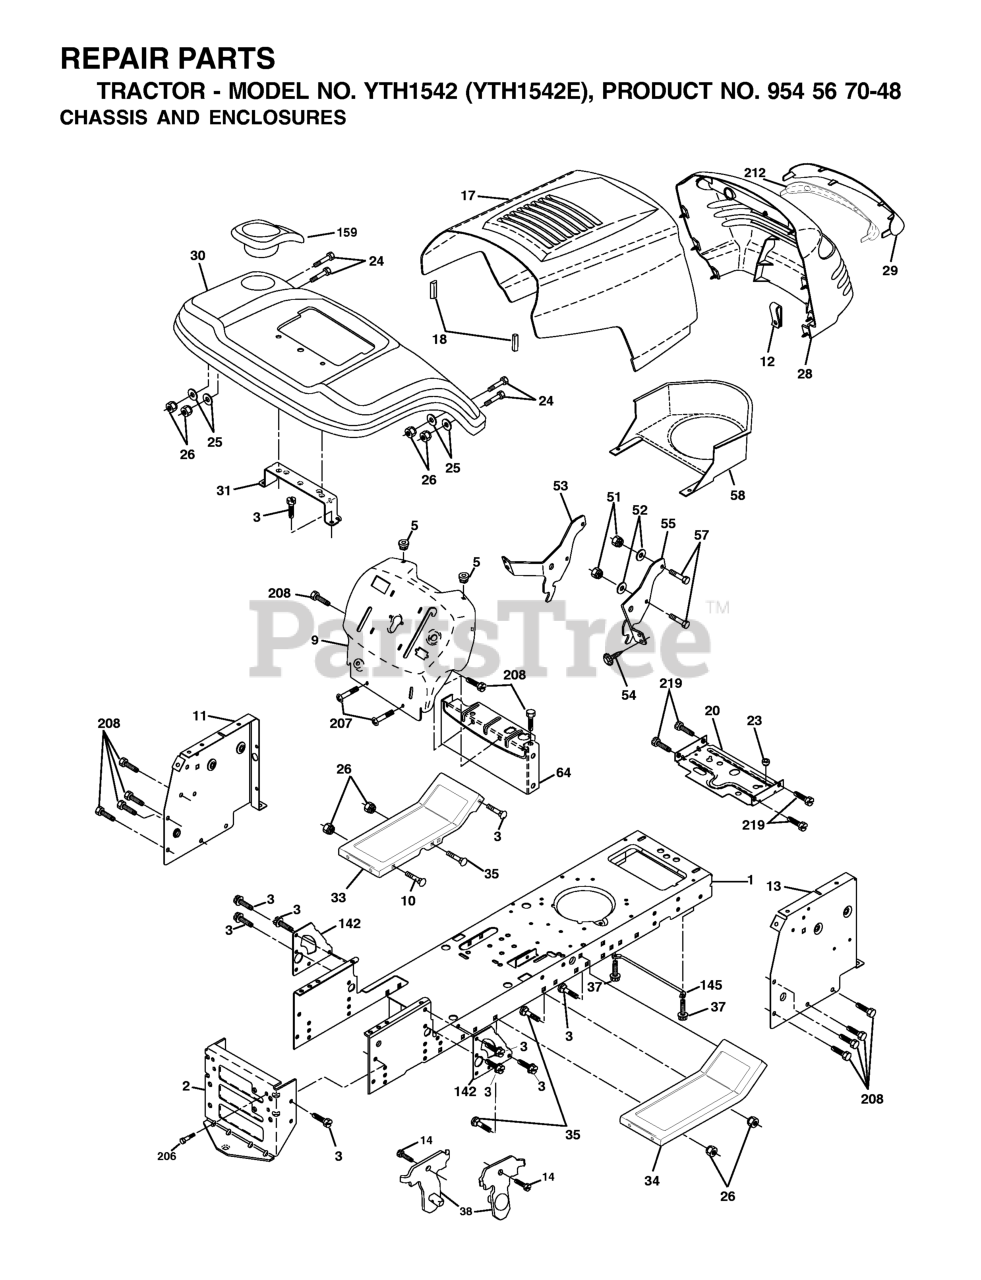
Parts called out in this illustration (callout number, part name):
1	CHASSIS STAMPING
2	DRAWBAR, 12GA
3	SCREW 3/8-16X3/4
5	BUMPER.RUBBER.HOOD
9	DASH(SUBS)
10	BOLT D
11	PANEL.DASH.LH.LTX
13	PANEL DASH RH
17	HOOD ASM.
18	BUMPER HOOD T
20	PLATE MTG.BATTERY/FUEL TANK
23	BUSHING.SNAP.NYL.BLK.
25	WASHER
26	NUT
28	GRILLE/LENS ASM
29	LENS
30	FENDER, YTH1746
31	BRACKET FENDER
33	FOOTREST PNT LH
34	FOOTREST PNT RH
37	Screw 5/16-18 x 1/2 Hex, Self Tapping 5/16-18 x 1/2
38	BRACKET.ASM.PIVOT.MOWER.REAR
51	LOCKNUT.NYLOC.1/4-20
53	BRACKET.GRILLE.LH
54	SCREW.HEX.WS.HD.8-18 X 7/8
57	BOLT
58	AIR DUCT P/L/LT
64	DASH LOWER
142	PLATE REINFORCEMENT
145	ROD PIVOT CHASSIS/HOOD
159	CUPHOLDER
206	SHOULDER BOLT 5/16-18TT
207	SCREW, 5/16-18 X 1/2
208	SCREW 3/8-16X1/2
212	REPL BY 532 1745-03
219	SCREW
